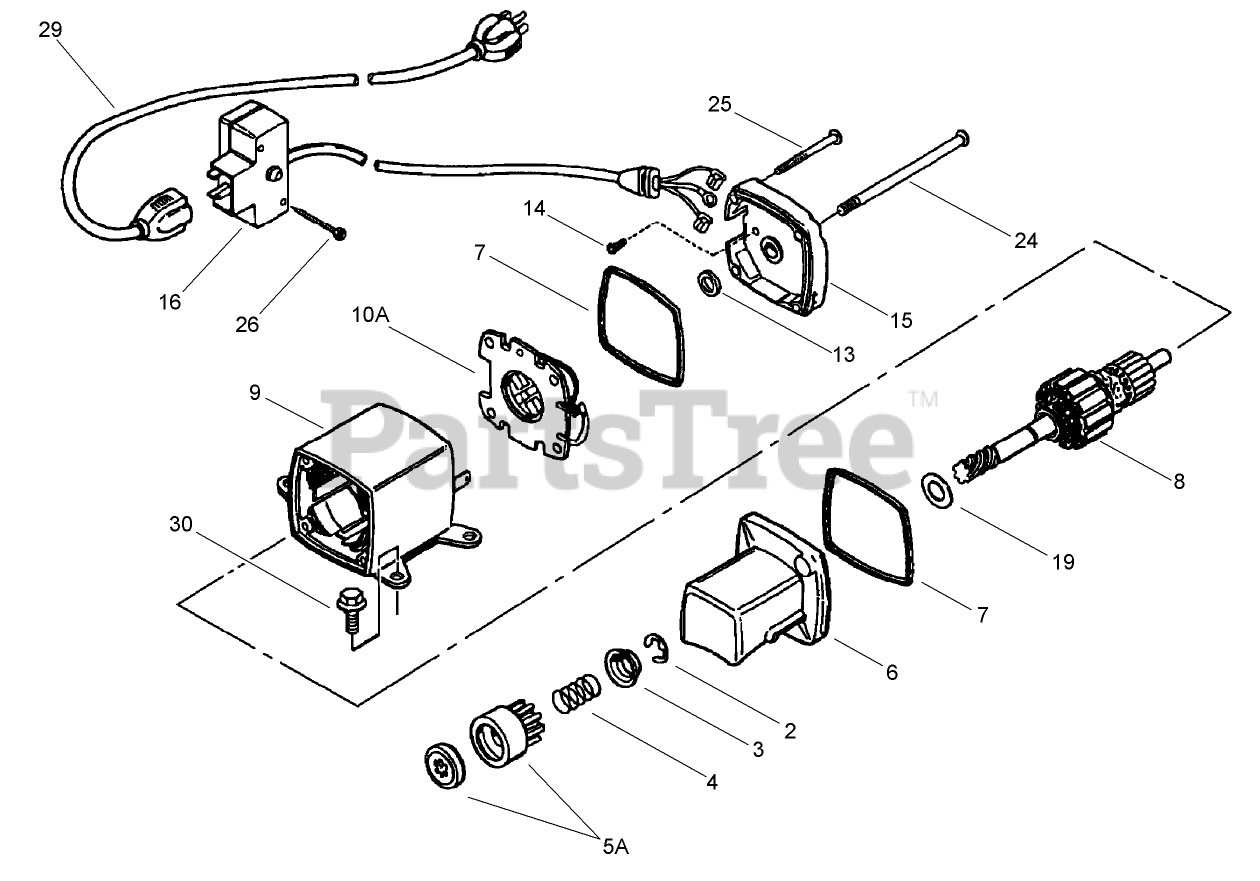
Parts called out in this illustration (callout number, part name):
2	Retainer-Ring
3	Retainer-Spring
4	Spring-Anti Drift
5A	Nut and Gear ASM (Includes 2)
6	Cap Assembly (Incl. Ref. #7)
7	O-Ring
8	Armature
9	Housing ASM (Must Purchase Complete Motor)
10A	Brush Card ASM
13	Washer-Thrust
14	Screw-Ground
15	Cap Assembly (Incl. Ref. #7)
16	Box Assembly-Switch (Incl. Ref. #26)
19	Washer-Thrust
24	Bolt-Case
25	Screw-Ground
26	Screw
26	Screw (12-16 x 5/8)
29	Cord-Extension (10-6)
30	Screw (T-30, 1/4-20 x 23/32)
